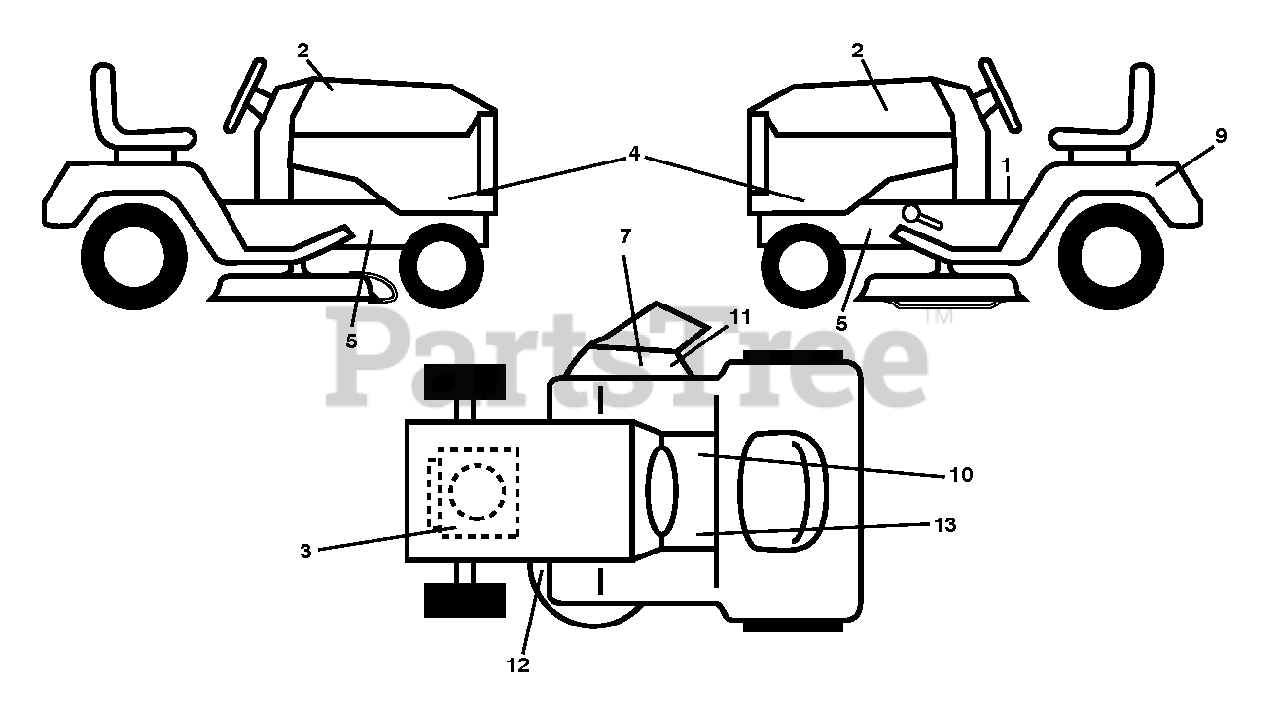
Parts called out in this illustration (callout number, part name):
1	DECAL.READ.OWN.MAN.SYMBOL.LT
2	DECAL.BADGE.170MM.TEXTLOGO.
3	DECAL.ENGINE.WARNING
4	DECAL.SDPNL.TEXLT.LT1597.HUSQ
5	DECAL.CHASSIS.HOT.MUFFLER
7	DECAL.CUTFINGER.CE.02
9	DECAL BTRY SYMBOLS
10	DECAL.FNDR.SDLE.BRAKE.CLUTCH.6
11	DECAL.DFLCTR.WARNNG.CTFNGR.SYM
12	DECAL.DECK.SCH.36,38,94.NONCR
13	DECAL.PARKING.BRAKE.SADDLE.LT
